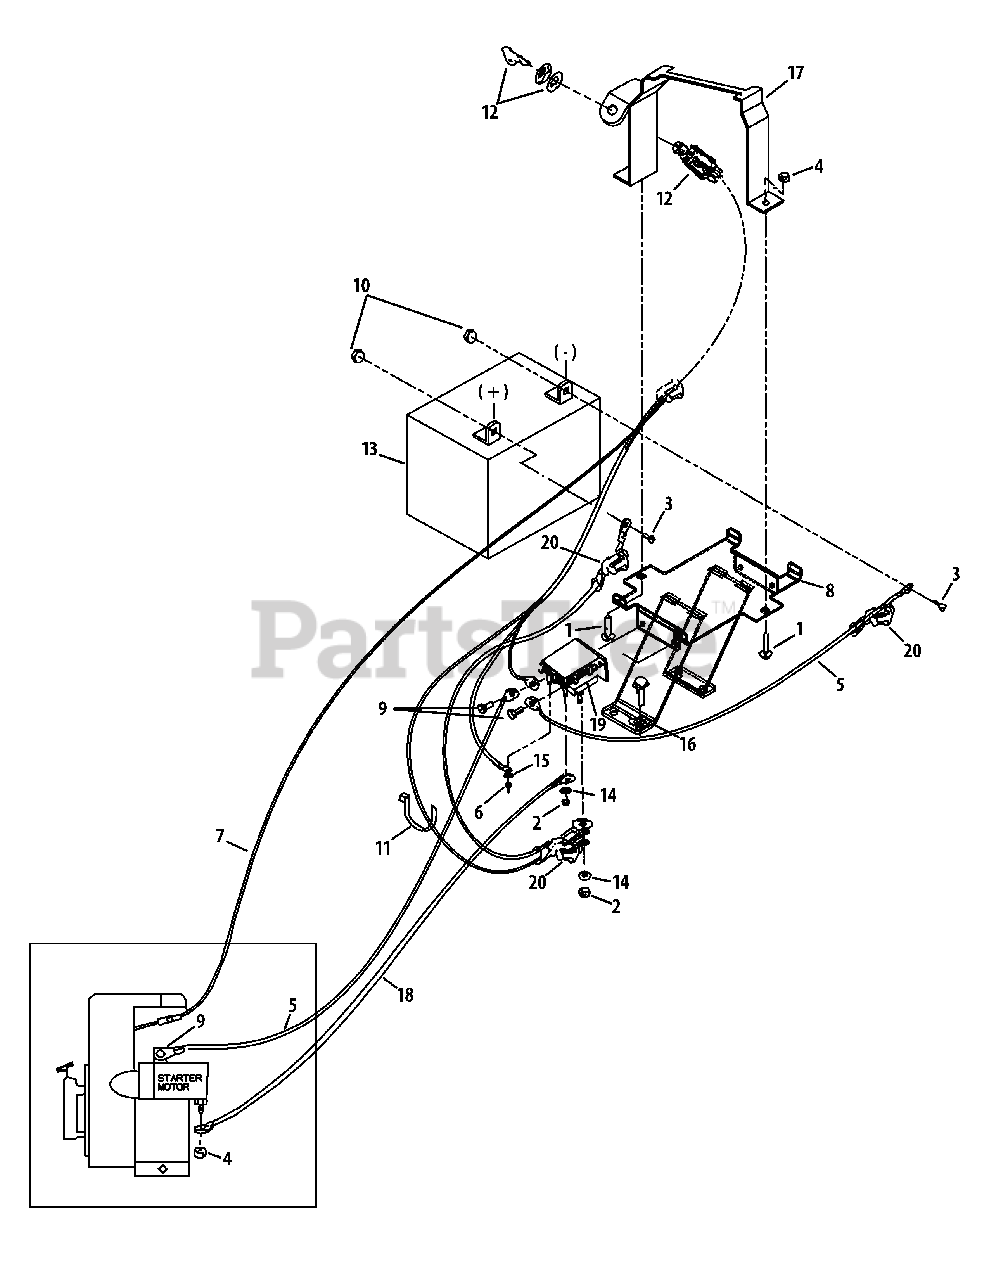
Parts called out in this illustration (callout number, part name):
1	Carriage Screw 1/4-20 x 1.25
2	Hex Nut 5/16-24
3	Flange Screw 1/4-20 x .625
4	Hex Locknut 1/4-20
5	Cable (Ground Wire)
6	Hexlock Washer Nut, 10-32
7	Electric Start Harness
8	Battery Bracket Assembly
9	Self-tapping Screw 1/4-20 x .5
10	Hex Nut 1/4-20
11	Cable Tie
12	Ignition Switch
13	Battery 270 CCA
14	Lock Washer 5/16
15	Lock Washer #10
16	External Lock Washer 5/16
17	Keyswitch Clamp
18	Cable (Solenoid to Starter Motor)
19	Solenoid (Incl. Nuts and Washers for Cables and Wires)
20	Insulating Boot
